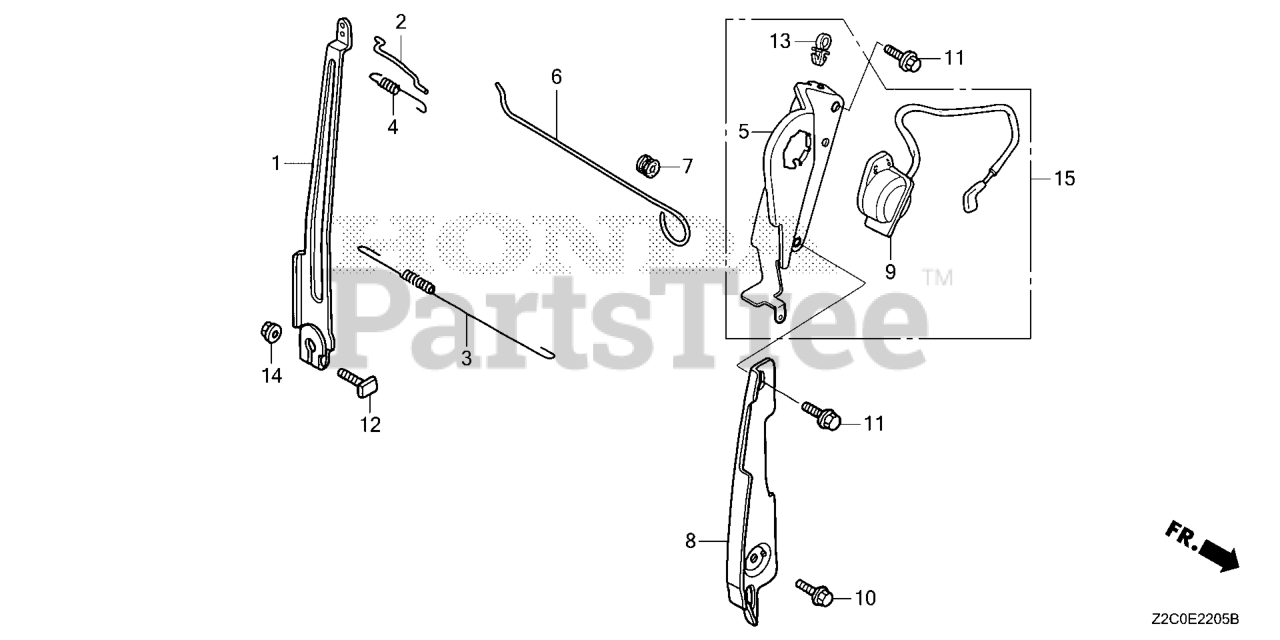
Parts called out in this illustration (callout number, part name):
1	ARM, GOVERNOR
2	ROD, GOVERNOR
3	SPRING, GOVERNOR
4	SPRING, THROTTLE RETURN
5	BASE, CONTROL
6	ROD, CHOKE CONTROL
7	GROMMET, CHOKE ROD
8	PLATE, SIDE
9	SWITCH ASSY., ENGINE STOP
10	BOLT, FLANGE (6X12) (CT200)
11	BOLT, FLANGE (6X14)
12	BOLT, GOVERNOR ARM
13	CLIP, CABLE (A)
13	HOLDER, WIRE (FASTEX)
14	NUT, FLANGE (6MM)
15	CONTROL ASSY.
